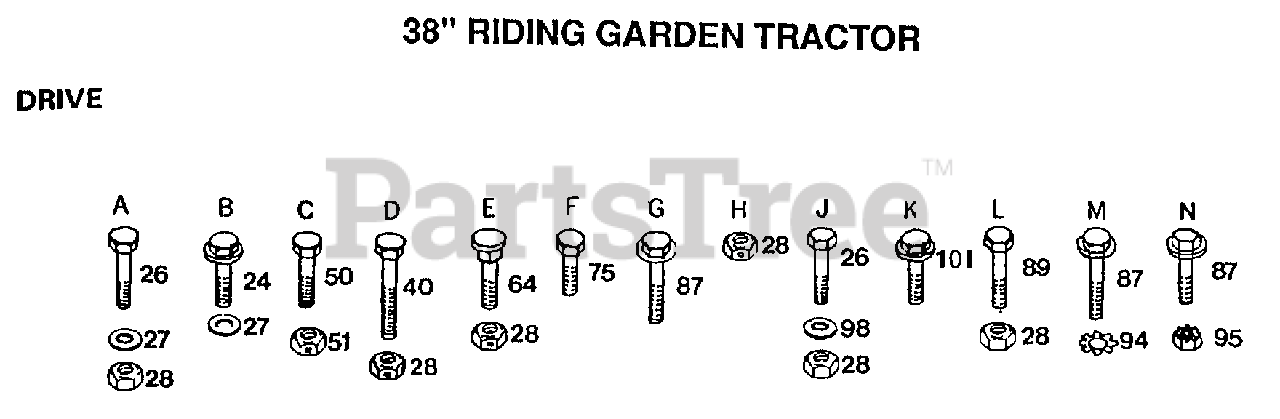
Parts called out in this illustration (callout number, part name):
24	SCREW
26	BOLT
27	WASHER
40	BOLT
50	BOLT
64	BOLT
75	SCREW LT
87	SCREW LT
94	LOCKWASHER
95	NUT
98	WASHER
101	SCREW
